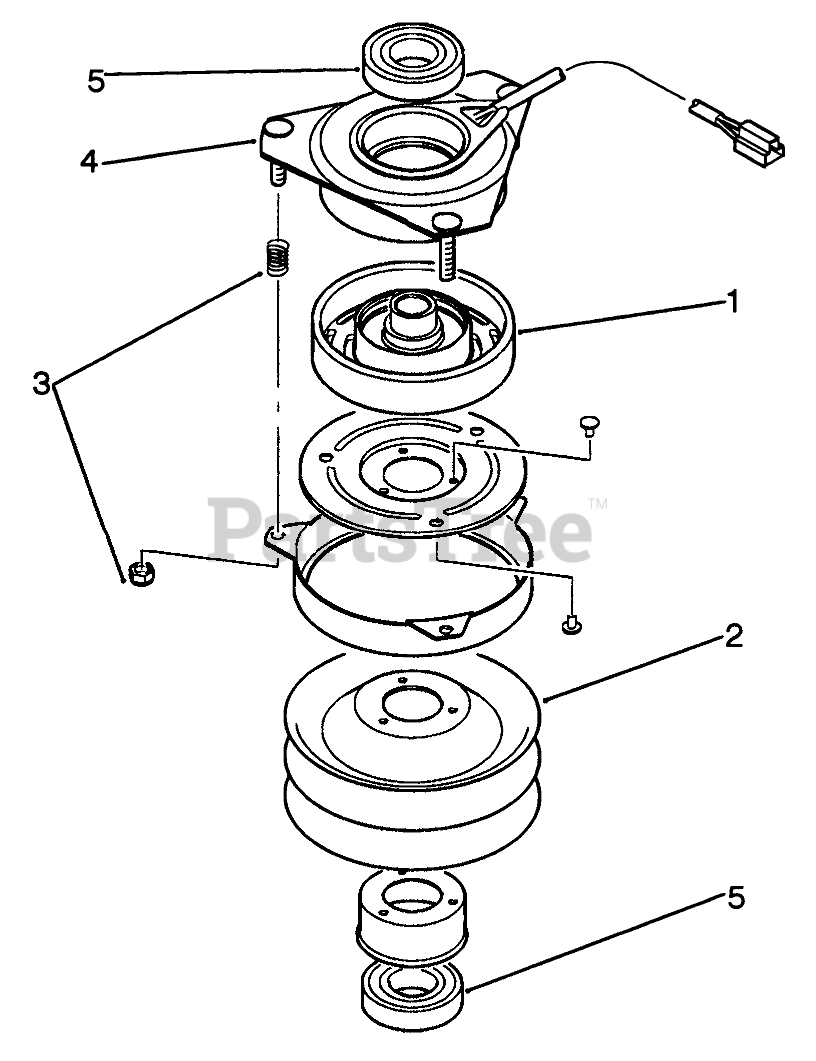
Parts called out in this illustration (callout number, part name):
1	ASS'Y-ROTOR
2	ASS'Y-ARMATURE
3	ACC-NUTS & SPRINGS
4	ASS'Y-FIELD
5	BEARING-ELEC CLUTCH
